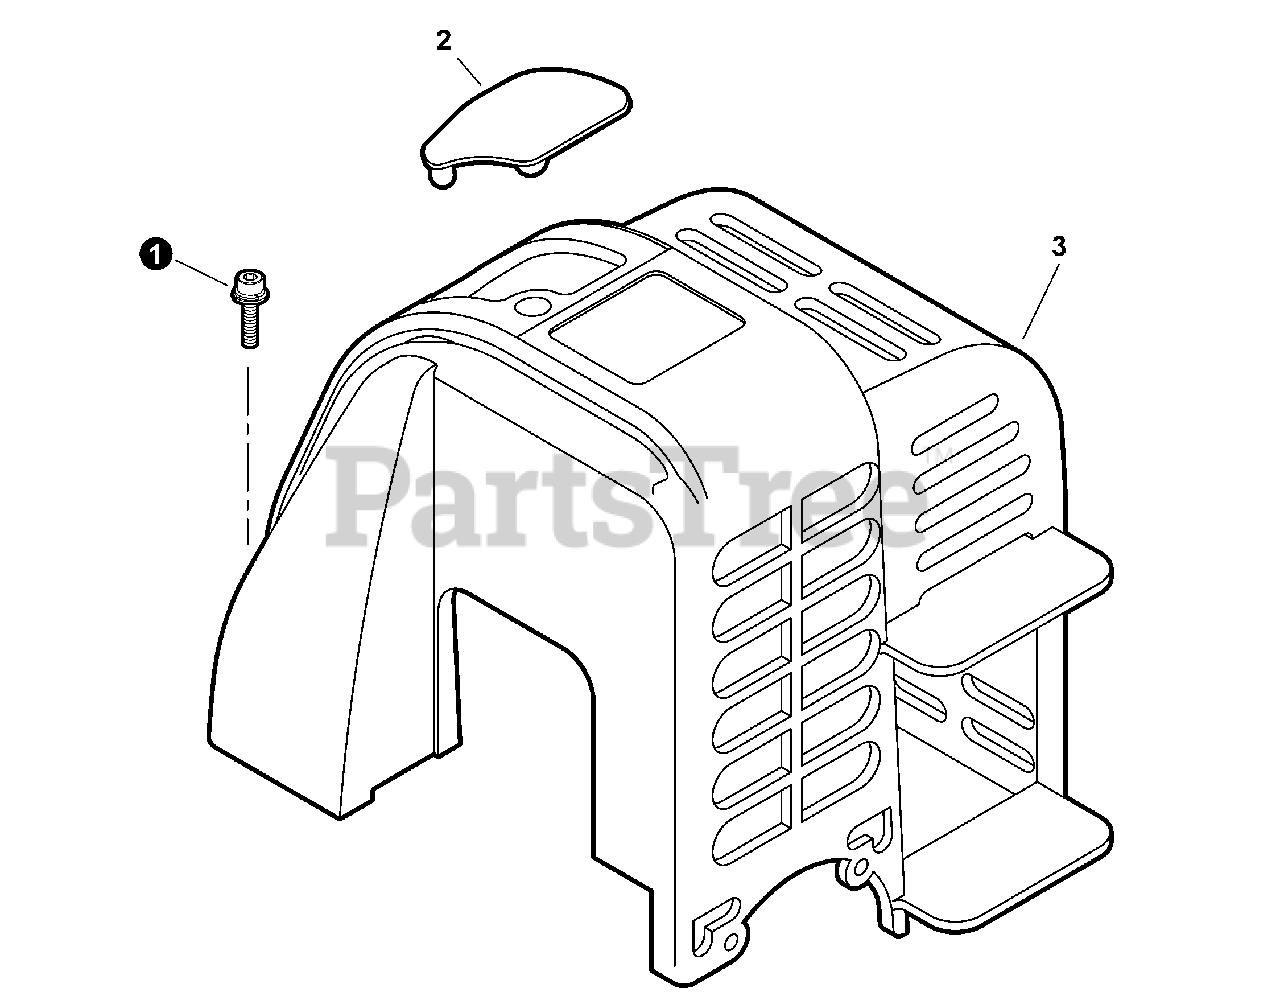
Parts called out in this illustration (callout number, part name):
1	BOLT M4x16
2	COVER, SPARK PLUG
3	COVER, ENGINE
